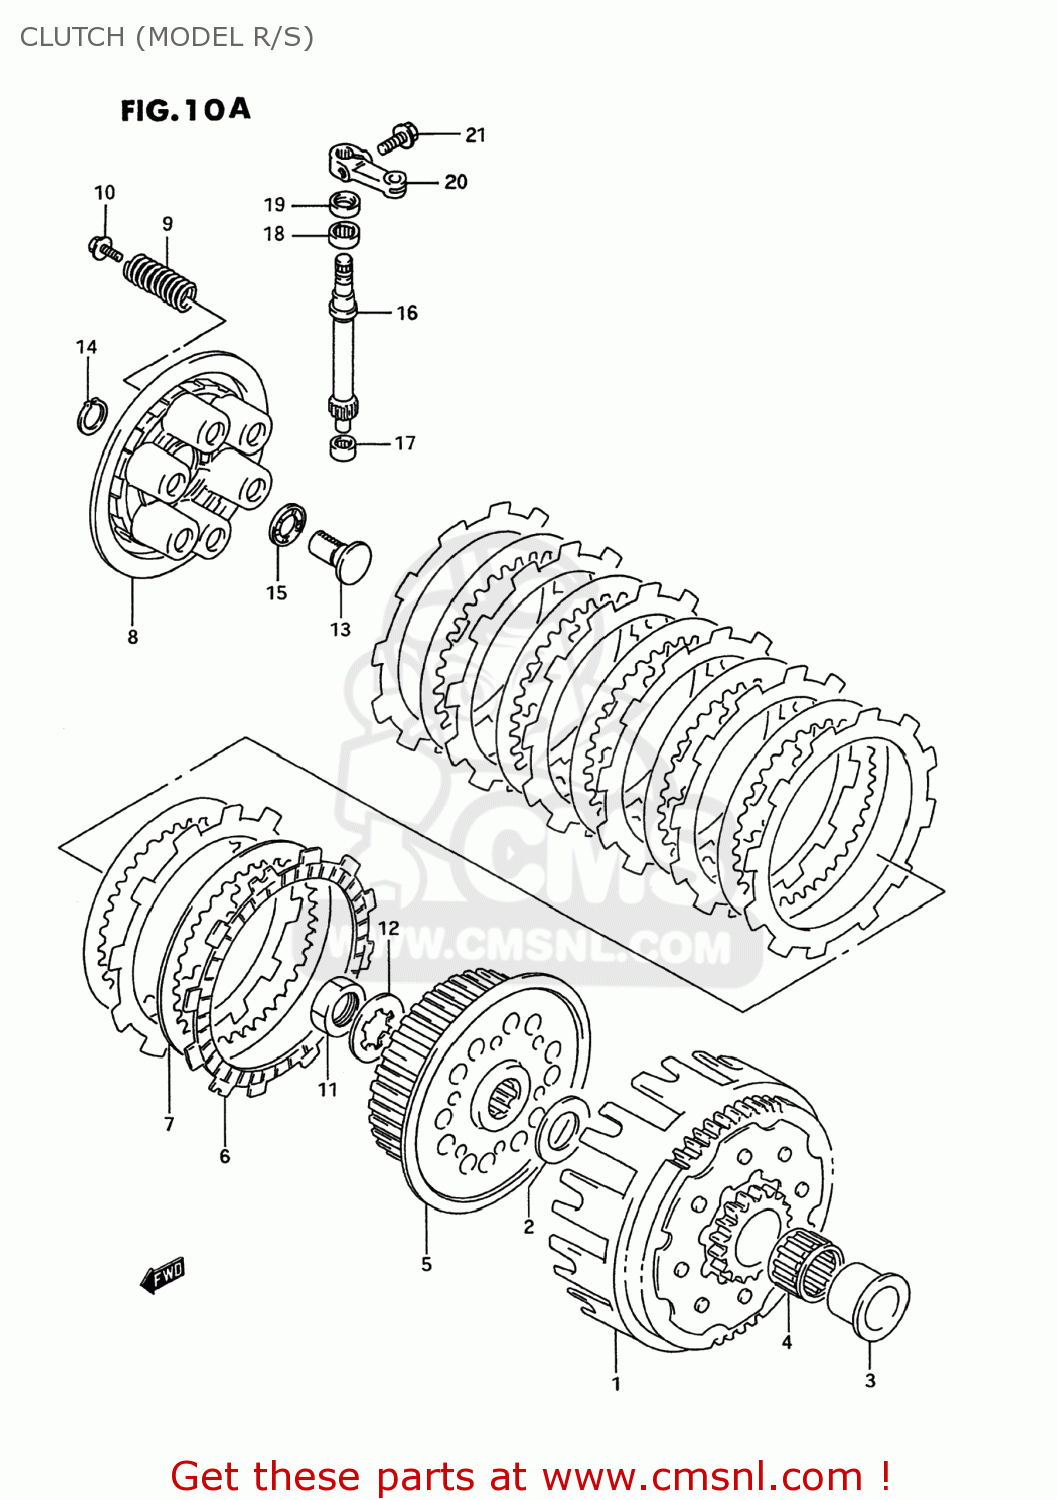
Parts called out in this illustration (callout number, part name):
1	GEAR ASSEMBLY,PRIMARY DRIVE
2	WASHER(22X38X2)
3	SPACER,PRIMARY DRIVEN GEAR
4	BEARING(29X34X21.8)
5	HUB,CLUTCH SLEEVE
6	PLATE,CLUTCH DRIVE (NAS)
7	PLATE,CLUTCH DRIVEN T: (NAS)
8	DISC,CLUTCH PRESSURE
9	SPRING
10	BOLT(5X25)
11	NUT
12	WASHER,LOCK
13	RACK,CLUTCH RELEASE
14	CIRCLIP,10MM
15	BEARING(10X22X2.8)
16	PINION,CLUTCH RELEASE(NT:12)
17	BEARING(9X13X10)
18	BEARING(12X16X10)
19	SEAL,OIL(10X17X5)
20	ARM,CLUTCH RELEASE
21	BOLT
